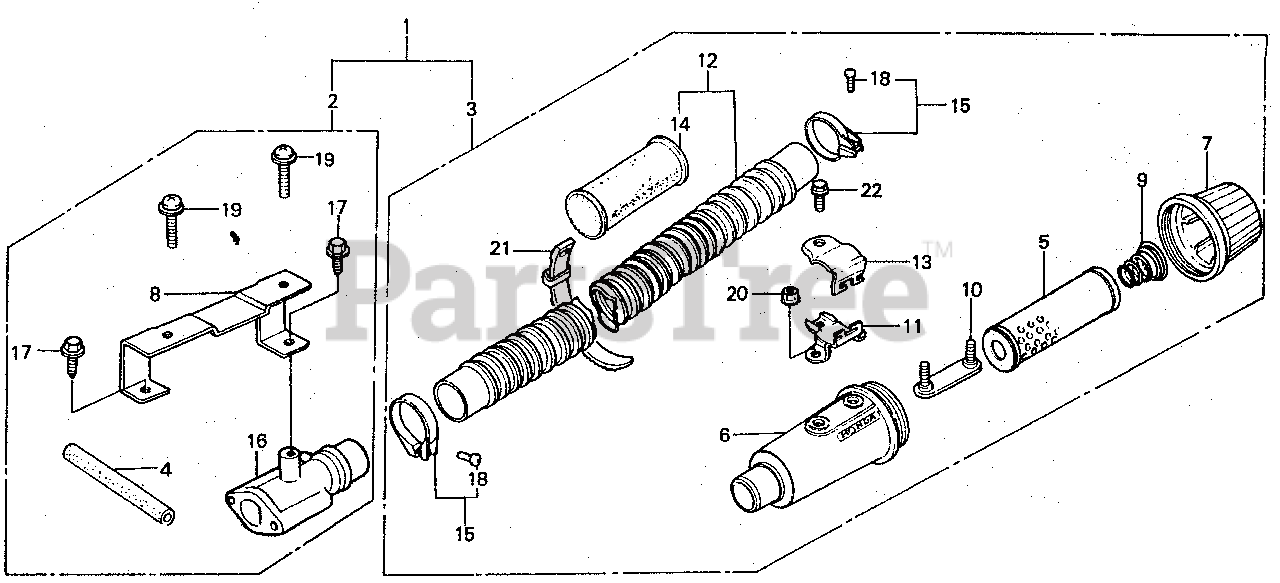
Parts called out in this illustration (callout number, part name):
1	AIR CLEANER KIT, SNORKEL JOINT
2	JOINT KIT, SNORKEL AIR CLEANER (N/A: SEE COMPONENTS)
3	AIR CLEANER KIT, SNORKEL (N/A: SEE COMPONENTS)
4	TUBE, BREATHER
5	ELEMENT, AIR CLEANER
6	HOUSING, AIR CLEANER
7	CAP, AIR CLEANER
8	STAY, CARBURETOR COVER
9	SPRING, SETTING
10	PLATE, AIR CLEANER SETTING
11	BRACKET A, AIR CLEANER
12	HOSE, AIR CLEANER
13	BRACKET B, AIR CLEANER
14	PROTECTOR, HOSE
15	BAND, AIR CLEANER CONNECTING TUBE (34)
16	JOINT, TUBE CONNECTING
17	BOLT, FLANGE (6X12) (CT200)
18	SCREW, PAN (4X25)
19	SCREW-WASHER (6X25) (NOT AVAILABLE)
20	NUT, FLANGE (6MM)
21	BAND B3, CABLE HARNESS
22	BOLT, FLANGE (6X16)
